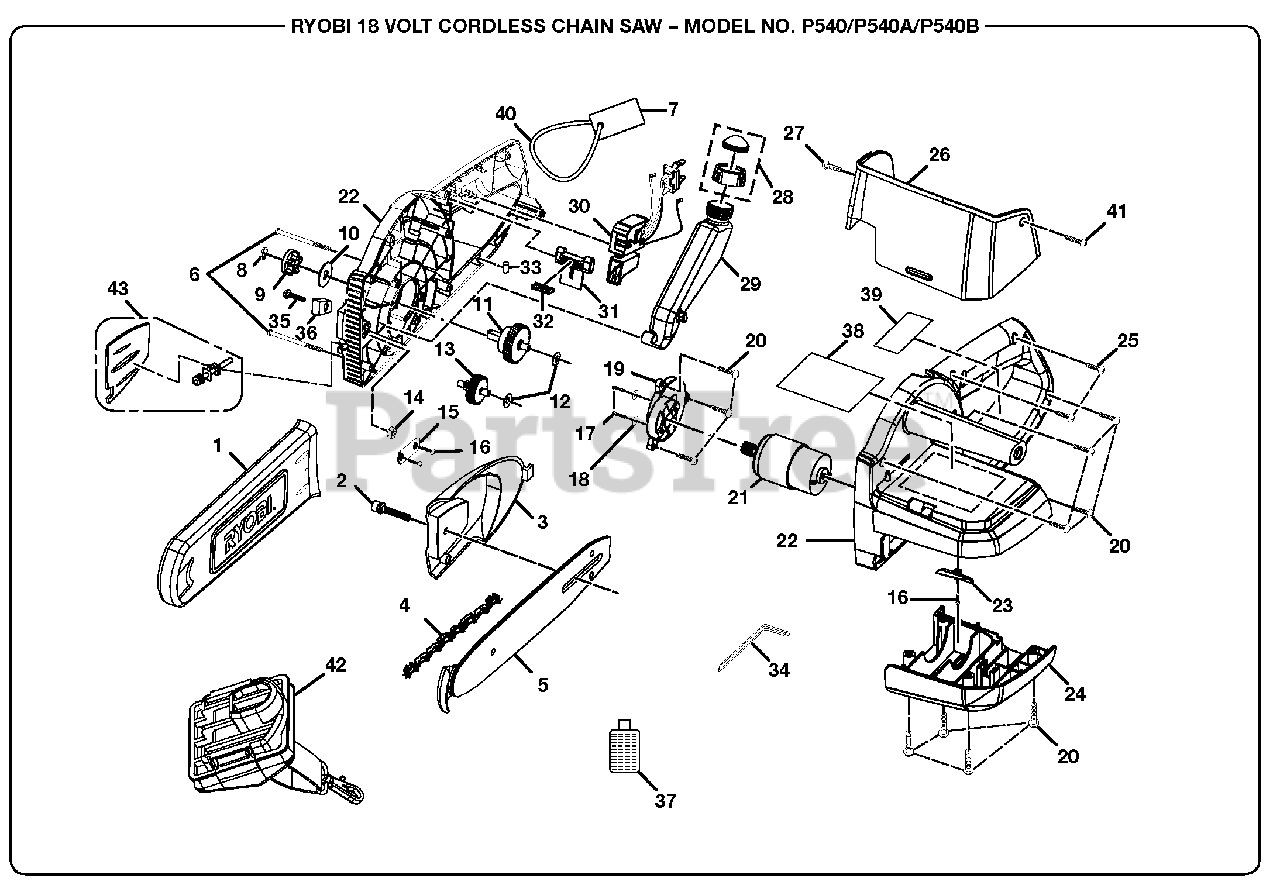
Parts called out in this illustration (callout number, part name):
2	SCREW (SOCKET HEAD)
3	SPROCKET GUARD
4	CHAIN, (90JG-040)
5	CHAIN BAR (10 in.)
6	SCREW (M4 X 66 mm)
7	WARNING LABEL
9	SPROCKET
10	COVER PLATE
11	OUTPUT SHAFT ASSEMBLY
13	OUTPUT SHAFT ASSEMBLY
14	HEX NUT (M6)
15	STEEL PLATE
16	BEARING RETAINER SCREW
17	SCREW (M4 X 12 mm)
18	SPRING WASHER
19	MOTOR MOUNTING ASSEMBLY
20	SCREW (M4 X 22 mm PAN HD.)
21	MOTOR ASSEMBLY
22	HOUSING ASSEMBLY
23	WIND PLATE
24	LOWER MOTOR HOUSING
25	SCREW (M4 X 16 mm PAN HD.)
26	FRONT HANDLE GUARD W/LABEL ASSEMBLY (INCL. KEY NO. 41)
27	SCREW (M3.5 X 25 mm)
28	OIL TANK COVER ASSEMBLY
29	OIL TANK
30	SWITCH ASSEMBLY
31	SAFETY KNOB
33	CONTACT PLATE STOPPER
34	HEX KEY (5 mm)
35	SCREW (M2.3 X 6 mm)
36	FELT SEAL
37	OIL AND BOTTLE ASSEMBLY
38	WARNING LABEL (ON HANDLE)
39	DATA LABEL
40	CABLE TIE
41	SCREW (M3.5 X 18 mm)
42	PLUG-IN LANYARD
43	CHAIN TENSION ASSEMBLY
